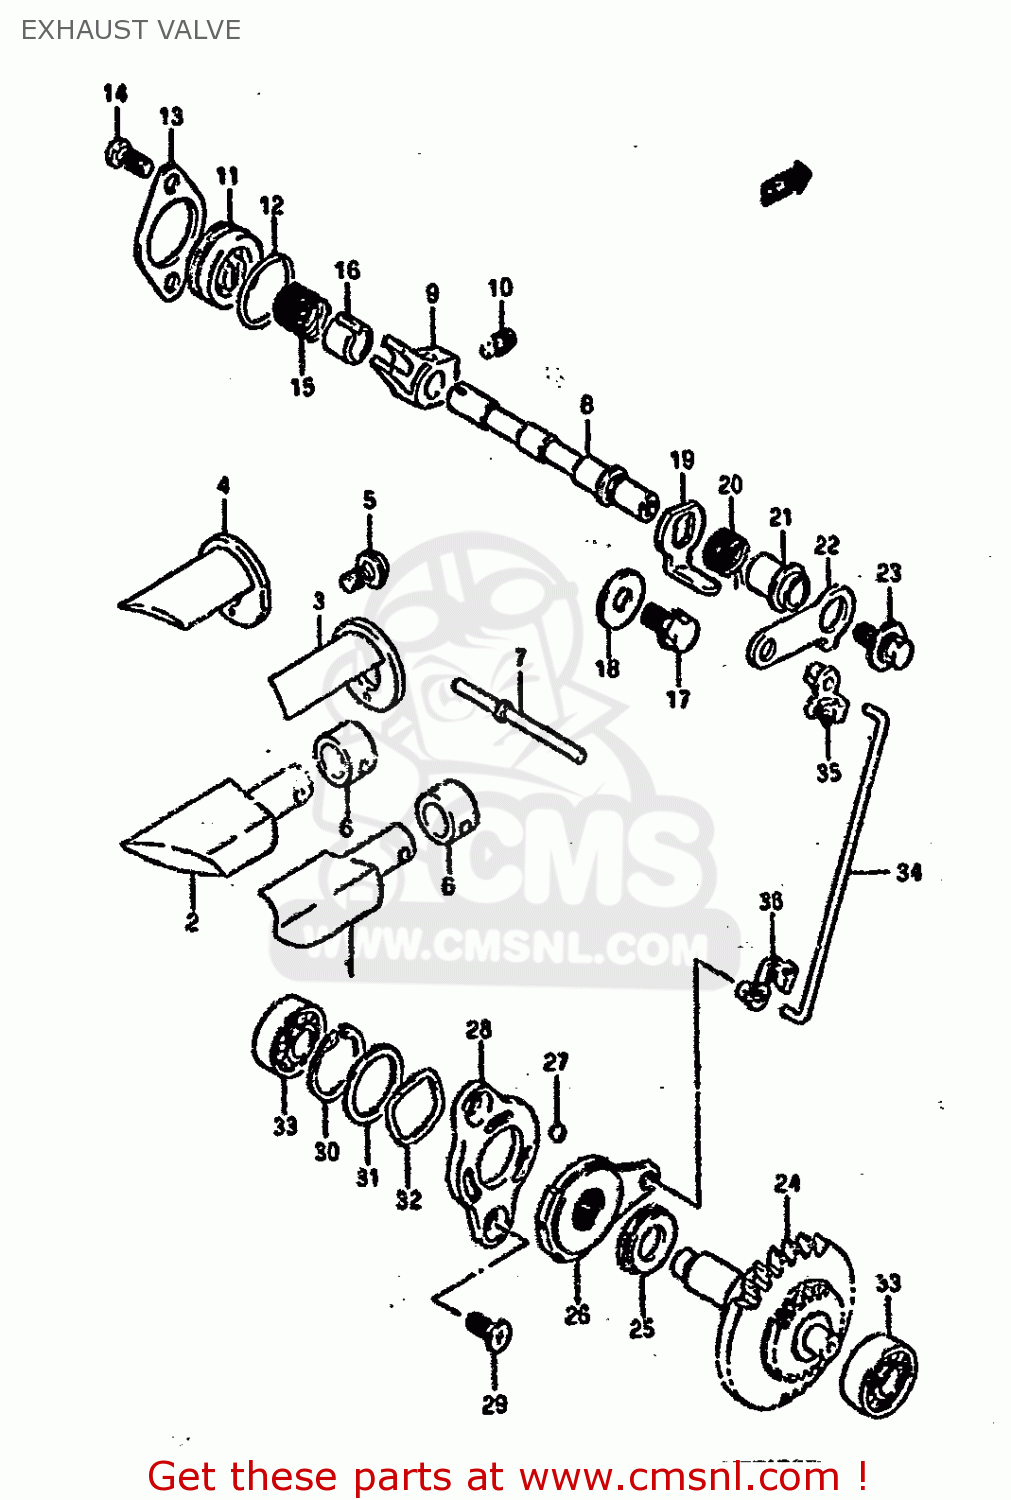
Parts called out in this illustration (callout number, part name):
1	VALVE,EXHAUST,R
2	VALVE,EXHAUST,L
3	GUIDE,EXHAUST VALVE,R
4	GUIDE,EXHAUST VALVE,L
5	SCREW
6	SPACER,EXHAUST VALVE
7	PIN,EXHAUST VALVE
8	SHAFT,EXHAUST VALVE
9	ARM,EXHAUST VALVE SHAFT
10	SCREW(6X10)
11	CAP,EXHAUST VALVE
12	O RING(D:1.9,ID:22.6)
13	RETAINER,EXHAUST VALVE
14	BOLT
15	SPRING
16	SPACER,EXHAUST VALVE SPRING
17	BOLT
18	WASHER
19	LEVER,EXHAUST VALVE NO
20	SPRING
21	SPACER,EXHAUST VALVE
22	LEVER,EXHAUST VALVE NO.1
23	BOLT
24	GOVERNOR ASSY,EXHAUST VALVE
25	BEARING(10X22X2.8)
26	ACTUATOR,EXHAUST VALVE
27	BALL
28	STARTER,EXHAUST VALVE ACTUATOR
29	SCREW(5X10)
30	CIRCLIP
31	SHIM(19.1X25X0.3)
32	WASHER
33	BEARING(8X22X7)
34	ROD,EXHAUST VALVE
35	BUSH,EXHAUST VALVE ROD NO.1
36	BUSH,EXHAUST VALVE ROD NO.2
